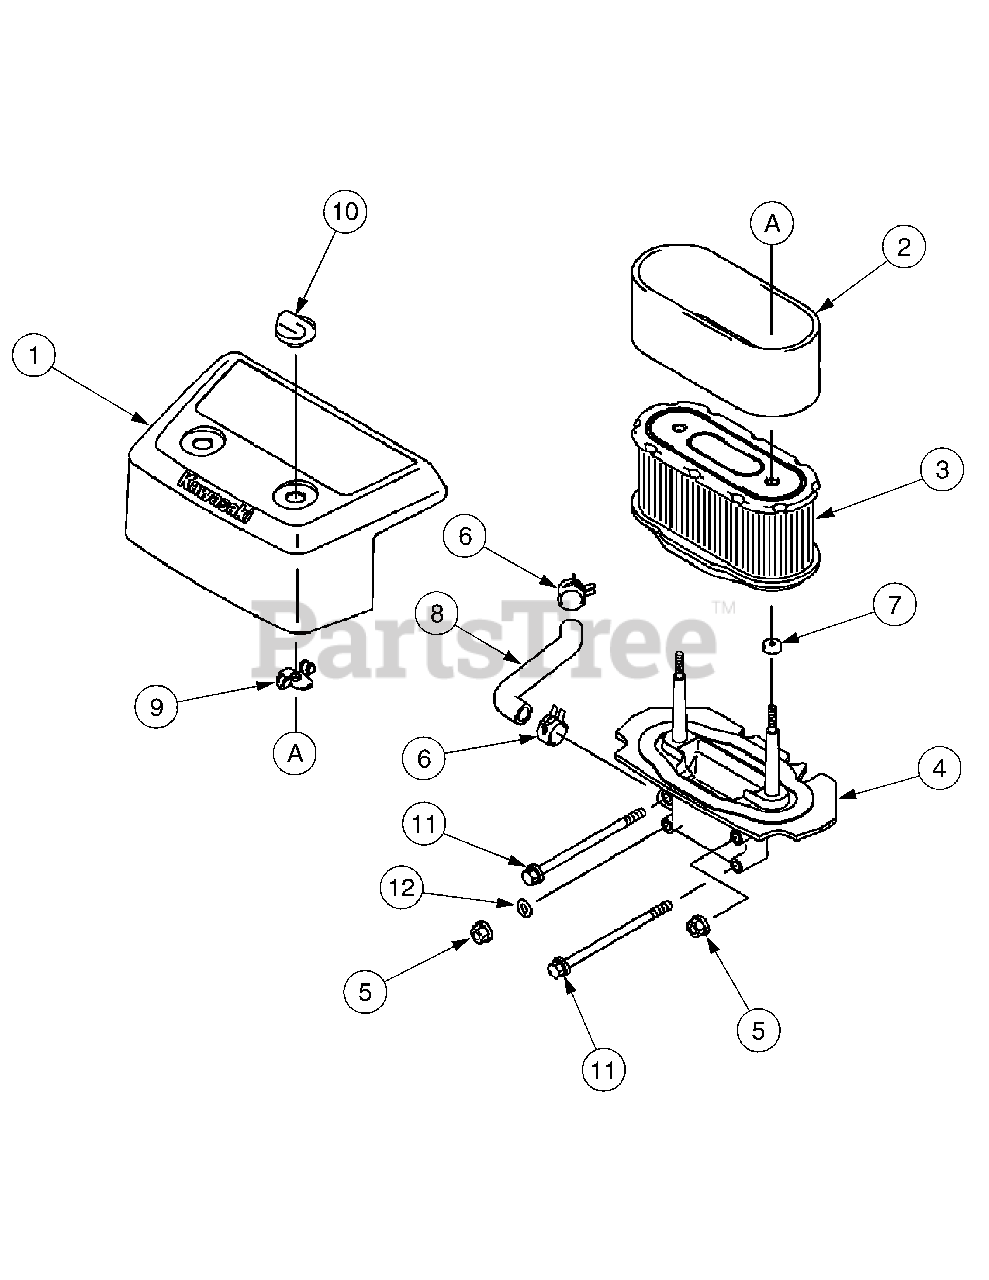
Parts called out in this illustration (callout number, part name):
1	Case, Air Filter
2	Element, Air Filter
3	Element, Air Filter
4	Pipe, Intake
5	Nut
6	Clamp
10	Nut
11	Bolt, Flanged
12	Washer, Plain
